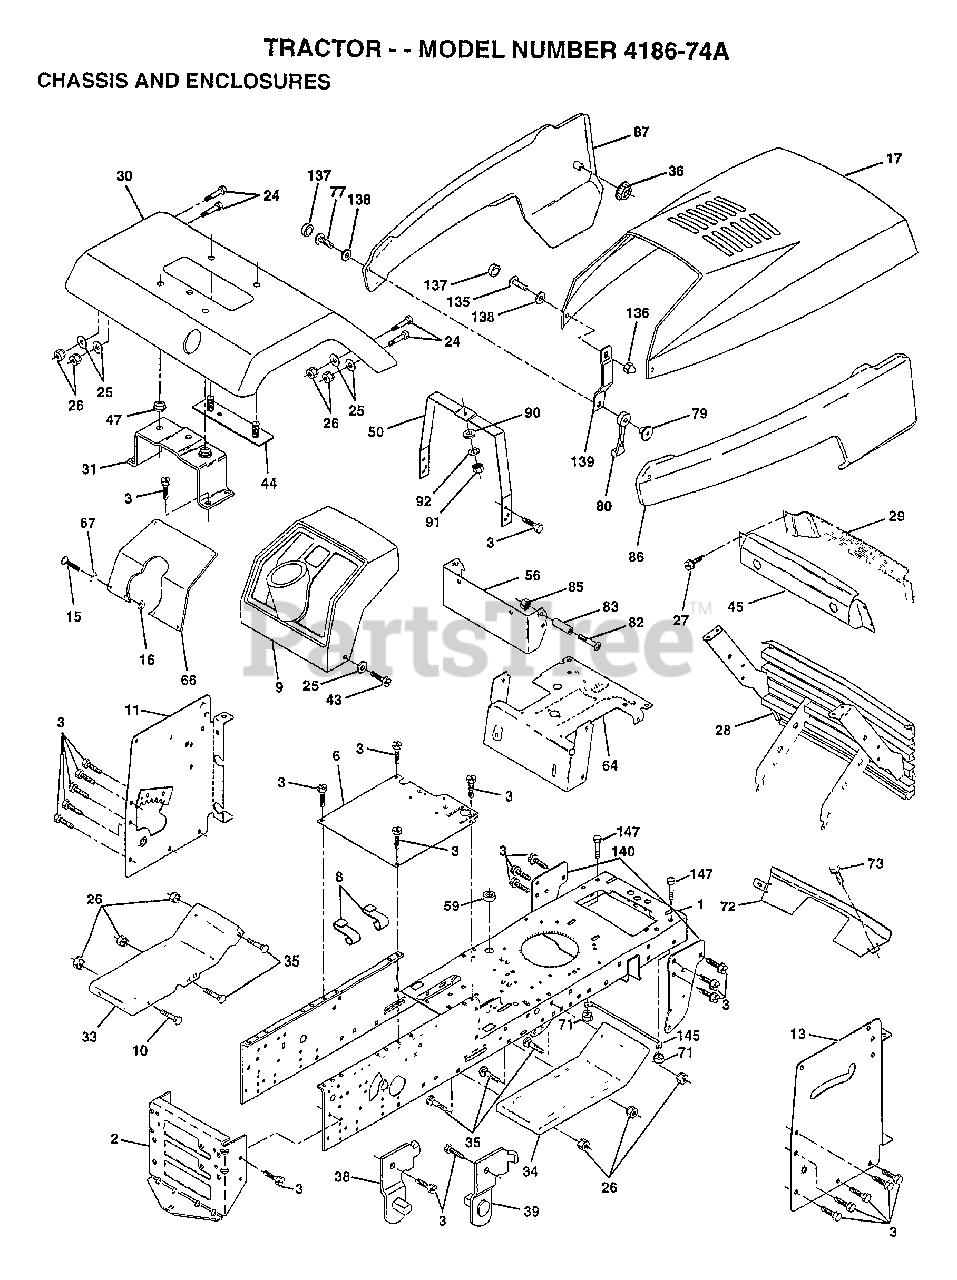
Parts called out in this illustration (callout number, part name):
1	CHASSIS ASM
3	SCREW
6	SADDLE
8	"CLIP,INSULATOR"
9	DASHBOARD BLACK
11	PANEL.DASH.LH.PNT
13	PANEL.DASH.RH.PNT
15	SCREW
24	BOLT
25	WASHER
26	NUT
28	GRILLE ASM PNT
29	LENS.BAR.CLEAR
31	BRKT.ASM.FENDER
33	FOOTREST.LH.LT/GT
34	FOOTREST.RH.LT/GT
35	BOLT
36	PAL NUT LT
38	BRACKET ASM LH
39	BRACKET ASM RH
43	SCREW
44	STRAP ASM FENDER
45	BEZEL.ASM.
47	NUT-PUSH YT
50	DASH.SUPT.YP/HUSQ
56	EXT DASH LTYT
64	DASH.LOWER.LT
66	"PLATE DASH,SLKSCR"
67	WASHER
72	STRAP.GRILLE.424
73	SCREW CRT
77	SCREW
79	WELDNUT
80	HOOD LATCH T
82	SCREW
83	SPACER LT
86	PANEL ASM SIDE RH
87	PANEL ASM SIDE LH
90	WASHER PM
92	LOCKWASHER
135	SCREW.10-24X3/8.
136	ACORN NUT RB
137	SNAP CAP LT
138	WASHER LT
139	BKT.SPT.HOOD/PANL
140	BRKT SUSPENSION
145	"ROD POVOT,CHASSIS"
147	BOLT LT
